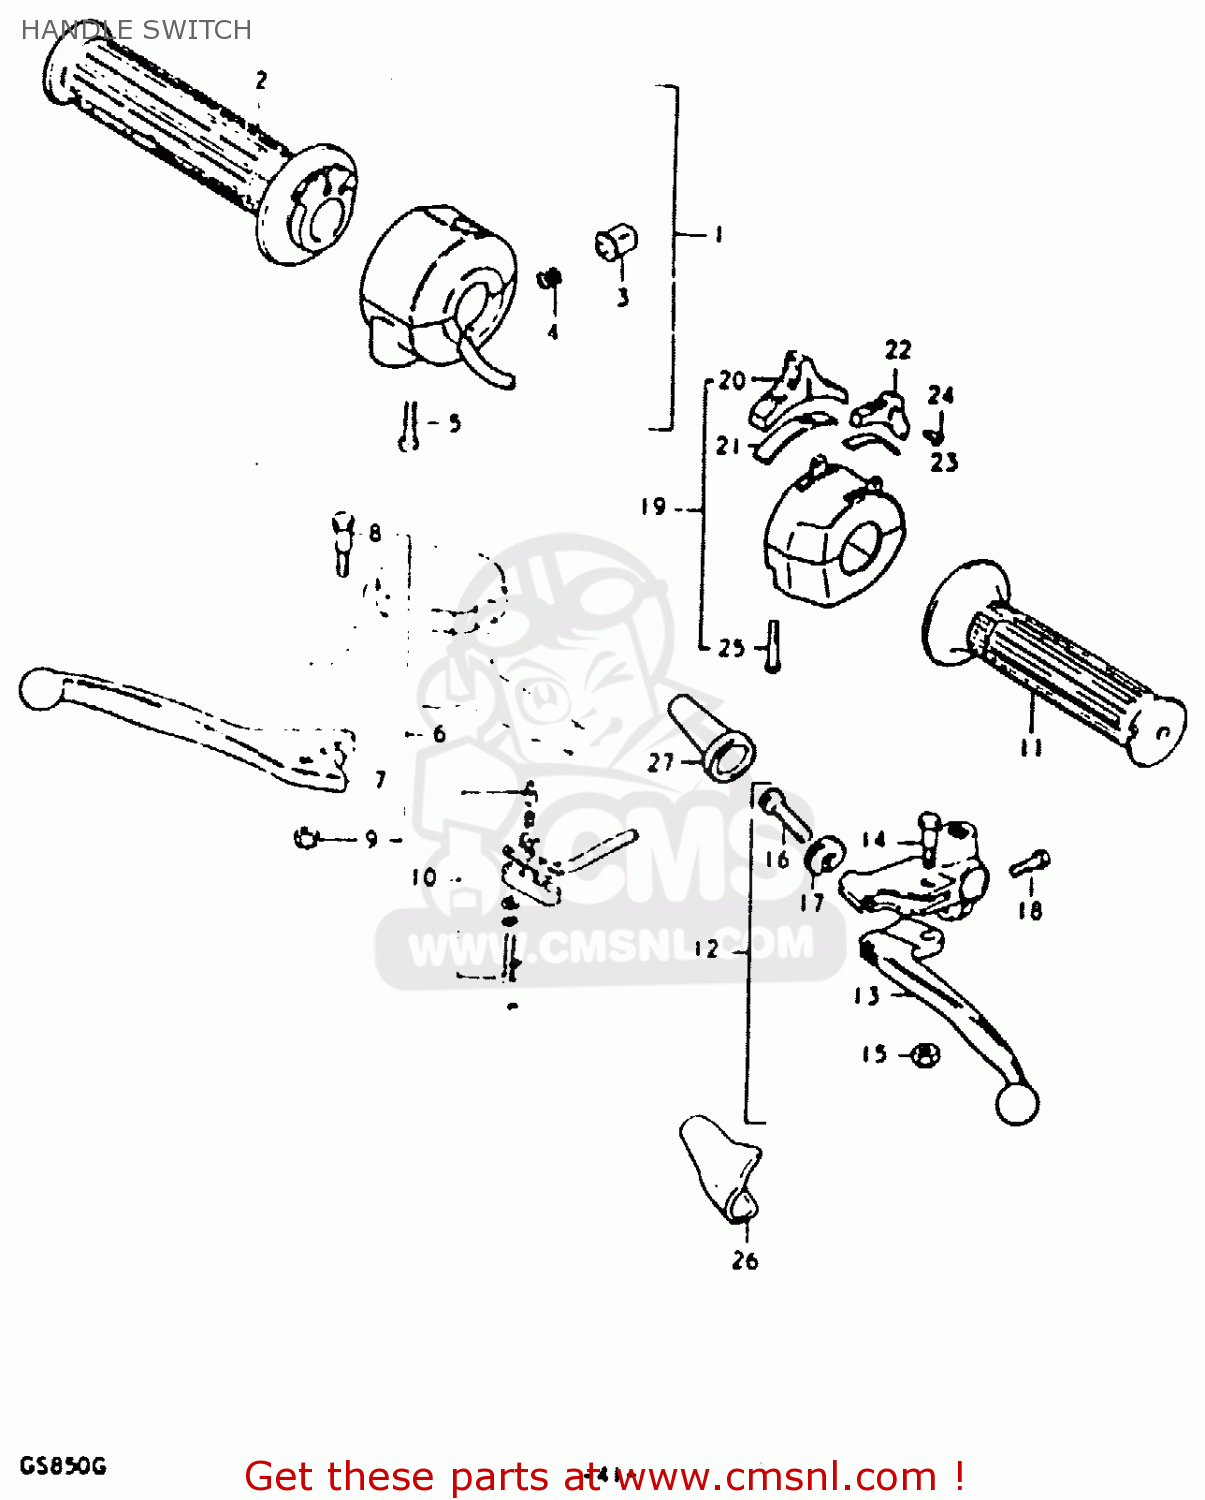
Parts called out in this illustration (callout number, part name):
1	GRIP ASSY, THROTTLE
2	GRIP,THROTTLE
3	BUTTON
4	SPRING
5	SCREW
6	LEVER ASSEMBLY,BRAKE
7	LEVER,BRAKE
8	BOLT,LEVER
9	NUT 6MM
10	SWITCH ASSY,STOP
11	GRIP,L
12	LEVER ASSEMBLY
13	LEVER,CLUTCH
14	BOLT,LEVER PIVOT
15	NUT 6MM
16	ADJUSTER,CABLE
17	NUT,CABLE ADJUSTER
18	BOLT
19	SWITCH ASSEMBLY,HANDLE,LEFT
20	KNOB,HANDLE SWITCH
21	PLATE,SWITCH KNOB
22	KNOB,DIMMER SWITCH
23	SPRING
24	SCREW
25	SCREW
26	COVER,CLUTCH LEVER
27	BOOT,CLUTCH CABLE
